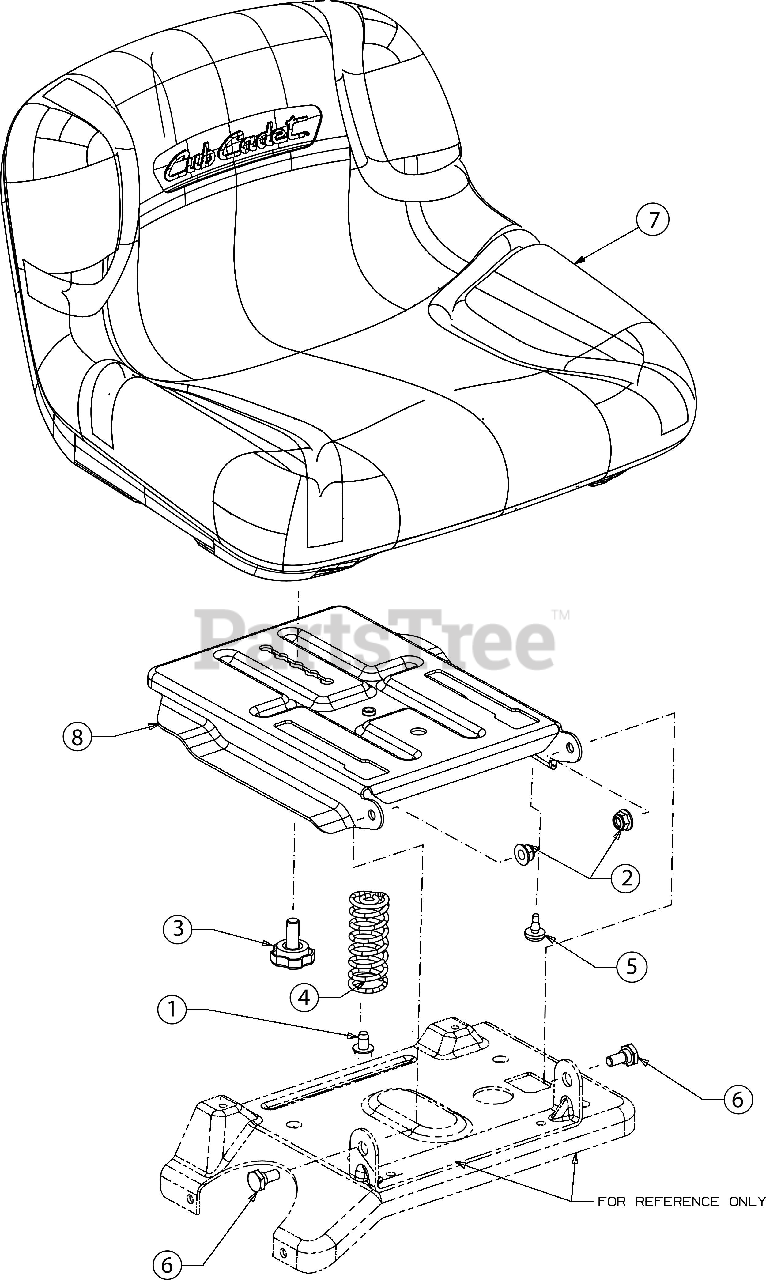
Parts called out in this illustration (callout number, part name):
1	SCREW 5/16-18 x .500
2	FLANGE LOCK NUT 5/16-18
3	SEAT ADJUSTMENT KNOB
4	SEAT SPRING
5	RUBBER BUMPER
6	SHOULDER SCREW .437
7	MEDIUM BACK SEAT (CUB)
8	MANUAL SEAT ADJUSTMENT BRACKET
